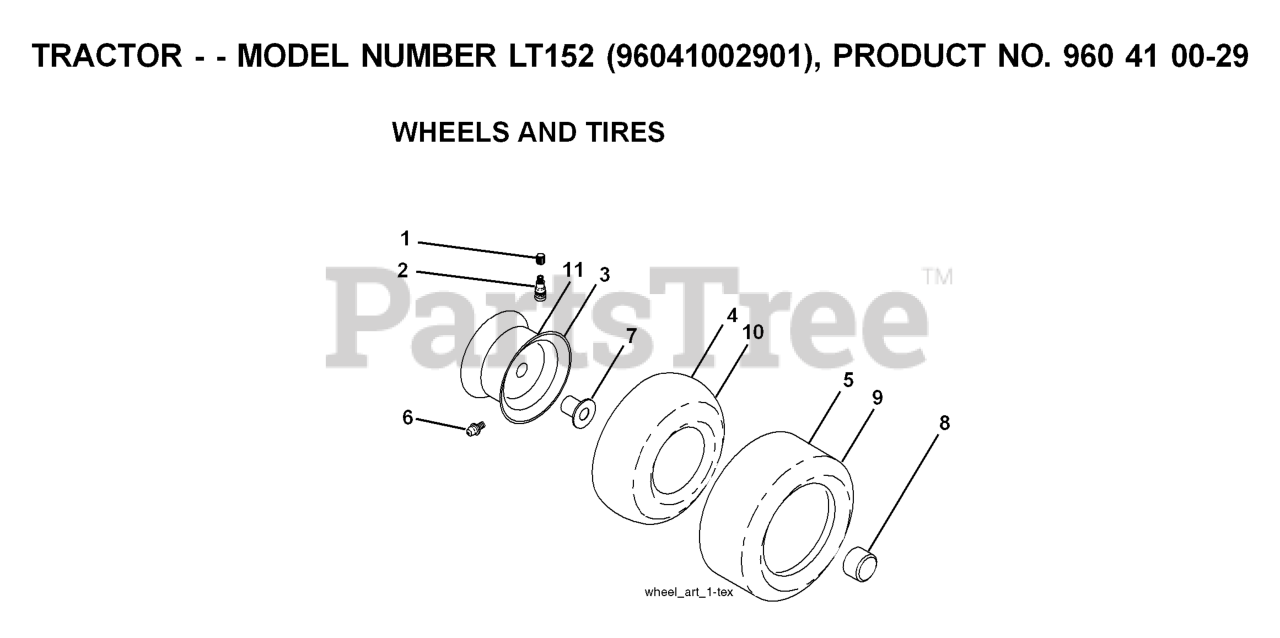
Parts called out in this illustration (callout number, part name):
2	VALVE STEM LT
3	RIM ASM 6" FRONT SILVER
4	TUBE.5.3/4.5/6
5	TIRE HEAVY DUTY
6	FITTING LT
7	BEARING T
8	CAP, AXLE BLK
9	TIRE HEAVY DUTY
10	TUBE
11	RIM ASM 8" REAR SILVER
